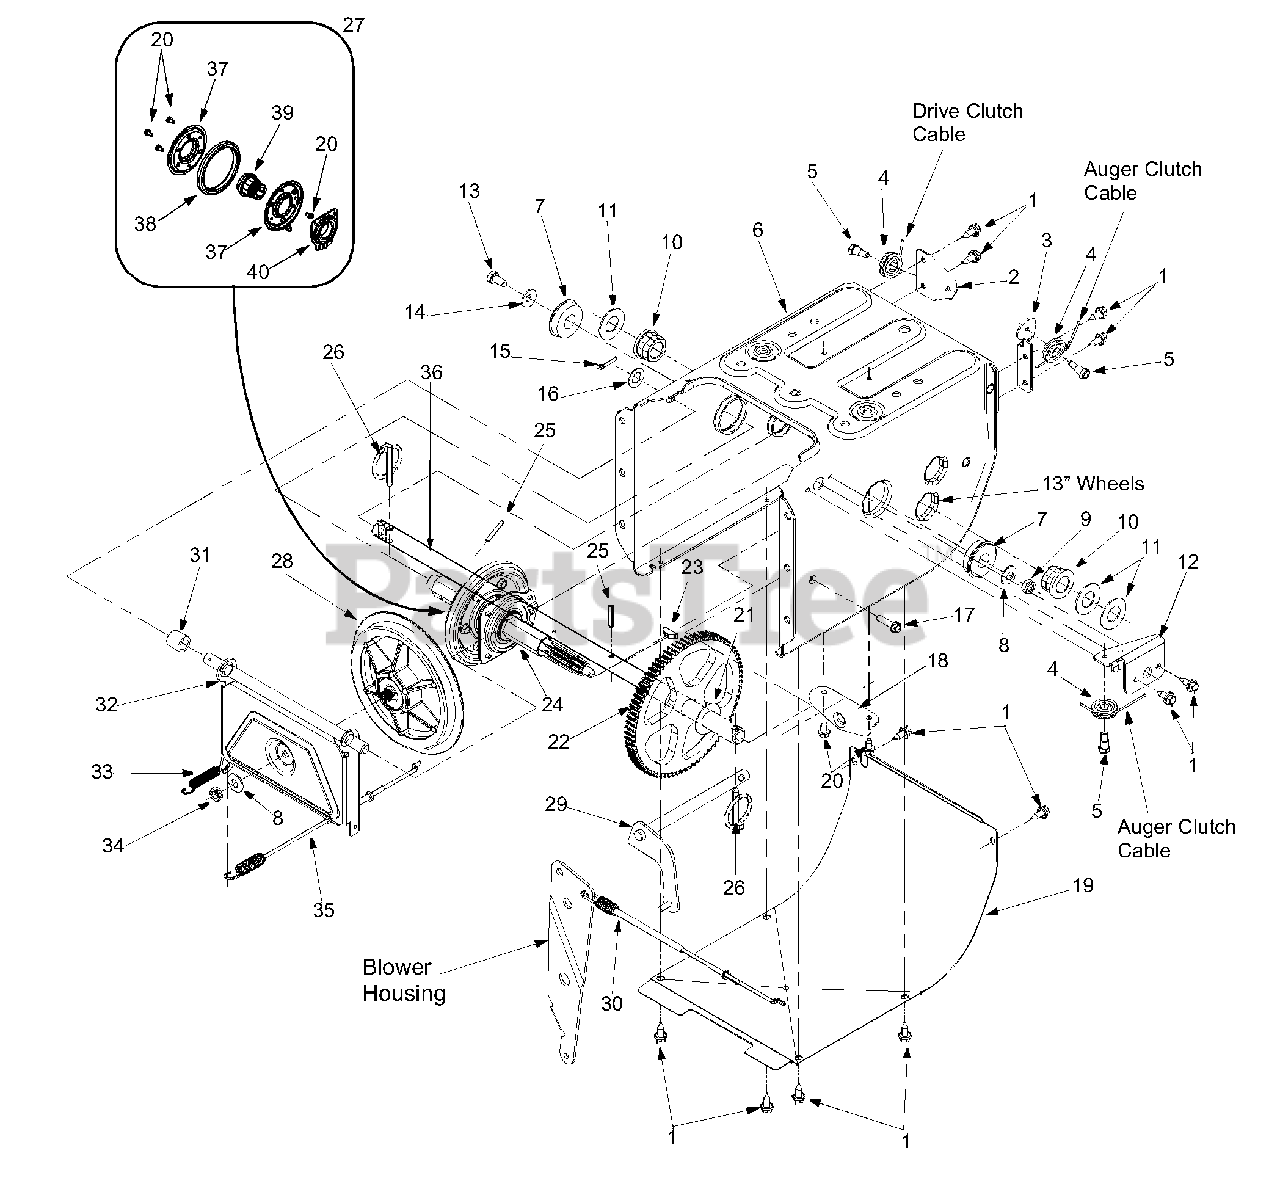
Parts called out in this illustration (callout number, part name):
1	Hex Screw
5	Hex Screw 1/4-28
8	Bell Washer
9	Lock Jam Nut
10	Hex Flange Bearing
11	Flat Washer
14	Bell Washer .340 ID x .872 OD
15	Cotter Pin
16	Flat Washer .536 ID x .930 OD
17	Hex Washer Screw 1/4-20
21	Flat Washer .760 ID x .50 OD
24	7-Tooth Shaft
25	Roll Pin
26	Klik Pin
27	Friction Wheel Assembly
28	Friction Disc Wheel
29	Wheel Shift Rod Assembly
30	Drive Cable, Auger
31	Spacer
34	Jam Nut 3/8-24
35	Drive Cable, Clutch
36	22 .2" Axle (Used w/ 13 x 4 tire);
36	21.4" Axle (Used w/ 13 x 5 tire);
37	Friction Plate
38	Friction Wheel Rubber
39	Friction Wheel Hub
40	Friction Wheel Bearing
